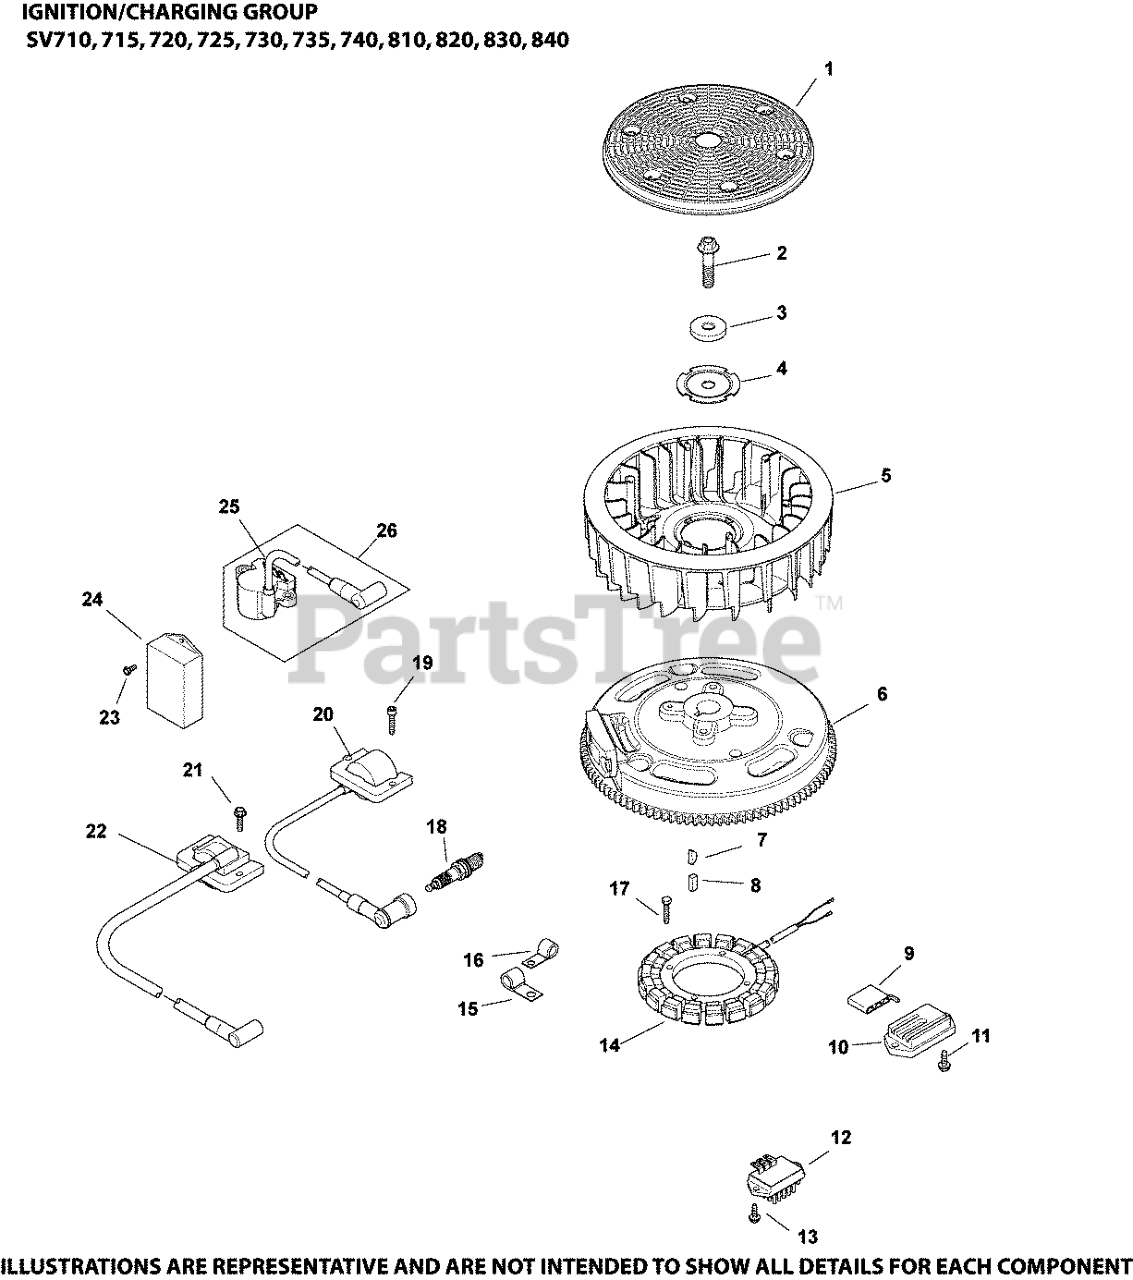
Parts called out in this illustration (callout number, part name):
1	SCREEN, GRASS
2	SCREW, FLG M10X1.5X45 - (#25086361S)
3	WASHER, FLAT 13/32"
4	PLATE, FAN MOUNTING
5	FAN USE 32 755 38-S
6	FLYWHEEL ASSEMBLY-USE 32 025 15-S
7	KEY, 3/16" X 5/8"
9	CONNECTOR, BODY (KM)-USE 25 155 41-S
10	REGULATOR/RECTIFIER USE 25 403 37-S
11	SCREW, HVY FLG M5X.8X16
14	KIT, 15 / 20 AMP STATOR
15	CLIP, CABLE
17	SCREW - USE M-548025-S
18	PLUG, SPARK (PRO SERIES)
20	MODULE,IGNITION
21	SCREW, FLG THD FRM M5X.8X20-(#25086399S)
23	SCREW, THD FRM M4X0.7X10
24	MODULE,DSAM CONTROL-USE 24 755 162-S
25	MODULE, DSAI ADV SPD-USE 24 584 89-S
